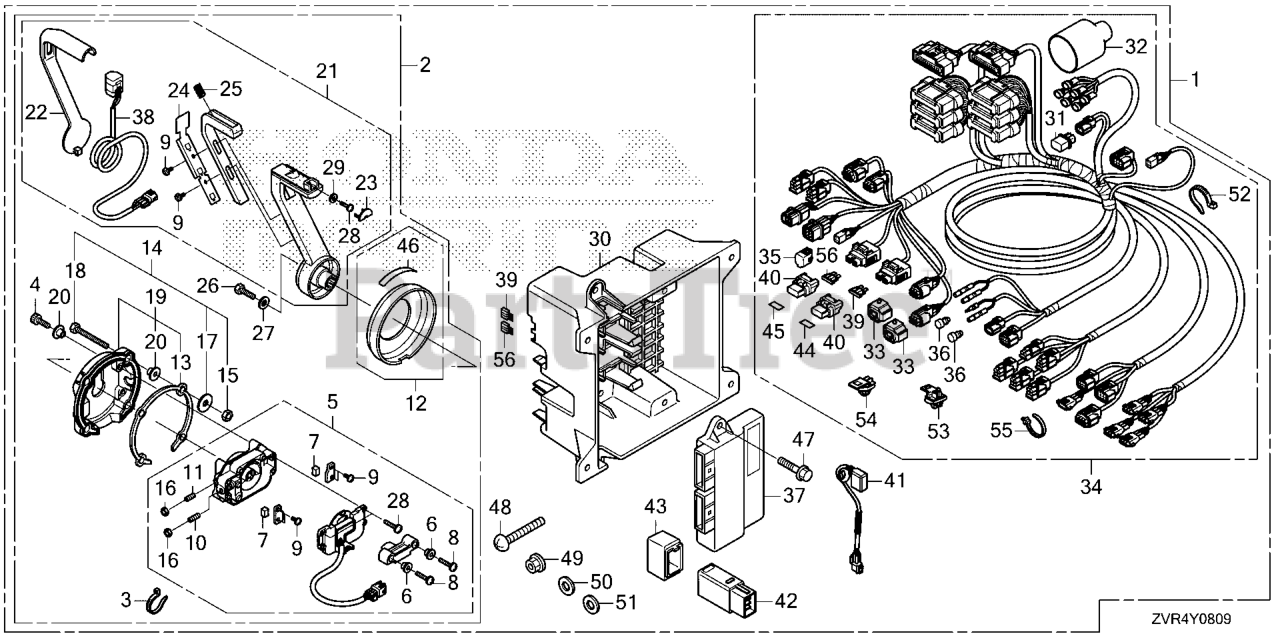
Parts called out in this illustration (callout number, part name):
1	BOX KIT, R/C
2	BOX ASSY., REMOTE CONTROL (FLUSH MOUNT)(RH)
3	BAND, NYLON
4	BOLT, SOCKET
5	HOUSING ASSY. (FLUSH MOUNT)
6	COLLAR, STOPPER
7	SHOE, BRAKE
8	SCREW
9	SCREW
10	SCREW SET
11	SCREW SET
12	COVER ASSY. (FLUSH MOUNT)
13	SHEET, WATERPROOF (FLUSH MOUNT)
14	NUT SET, MOUNTING
15	NUT, NYLON
16	NUT
17	WASHER
18	BOLT
19	BASE ASSY. (FLUSH MOUNT)
20	COLLAR, BASE
21	LEVER ASSY. (FLUSH MOUNT)
22	PANEL, LEVER (FLUSH MOUNT)
23	CAP, LEVER (FLUSH MOUNT)
24	PLATE, LEVER PANEL
25	SPRING, COIL
26	BOLT
27	WASHER
28	SCREW
29	WASHER
30	CASE, CONTROL UNIT
31	TERMINATOR ASSY.
32	COVER, CONNECTOR (NOT AVAILABLE)
33	SUSPENSION, CONNECTOR
34	CABLE, REMOTE CONTL
35	CAP, DUMMY (WPC 4P 090 M) (RED)
36	PLUG, CONNECTOR (INNER) (TROLLING CONTROL)
37	UNIT ASSY., CONTL
38	SWITCH ASSY., POWER TRIM-TILT (FLUSH MOUNT)
39	FUSE, BLADE (3A)
40	COVER ASSY., FUSE
41	RELAY ASSY., CONTROL (NOT AVAILABLE)
42	RELAY ASSY., MAIN
43	SUSPENSION, RELAY
44	LABEL, FUSE (3A)
45	LABEL, FUSE (5A)
46	MARK, FLUSH MOUNT
47	BOLT, FLANGE (6X20)
48	SCREW, PAN (5X40) DUAL QTY = (8) (SINGLE)
49	NUT, FLANGE (5MM)
50	WASHER, PLAIN (5MM)
51	WASHER, SPG (5MM)
52	HOLDER, CONNECTOR (128.6MM) (NATURAL)
53	CLIP, CONNECTOR (DARK BLUE)
54	CLIP, CONNECTOR (DARK BROWN)
55	CLIP, HARNESS BAND (145MM) (BLACK)
56	FUSE, MINI (5A)
